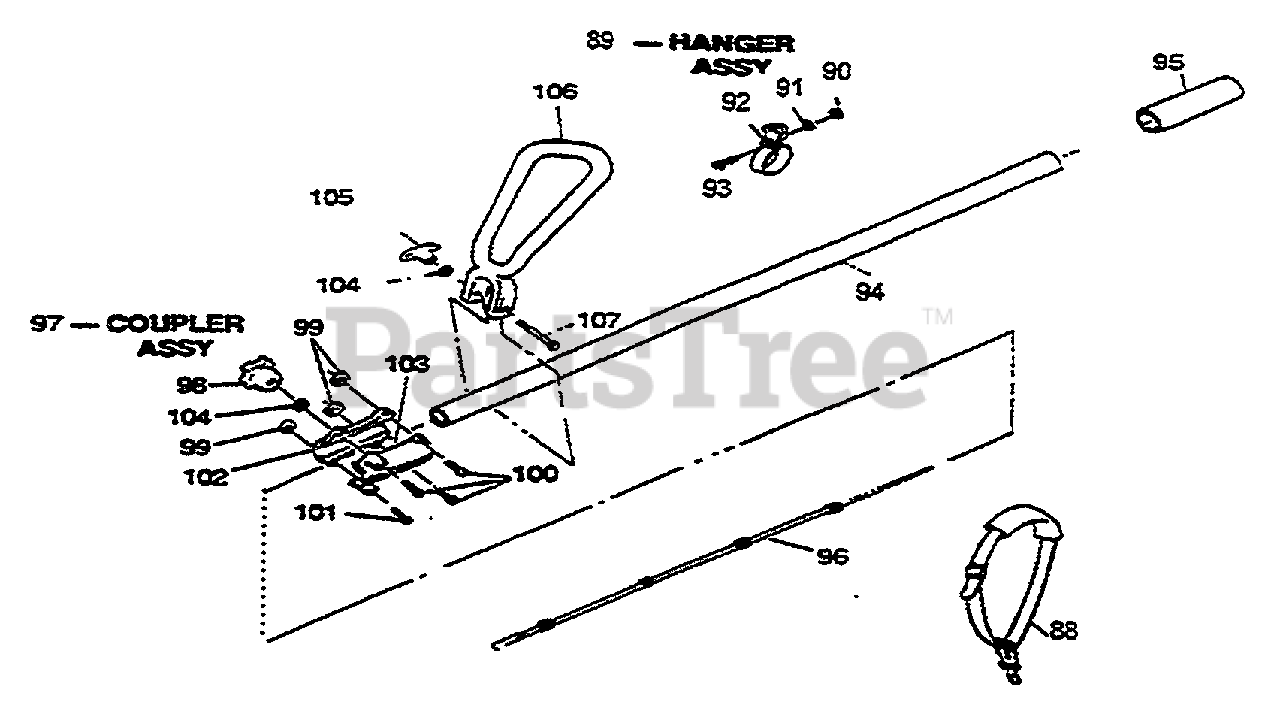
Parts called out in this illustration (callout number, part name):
88	HARNESS
89	HANGER ASSY
92	HANGER
94	TUBE ASSY
96	LINER & SHAFT ASSY
97	COUPLER ASSY
98	KNOB
100	BOLT
102	COUPLER RH.
103	COUPLER LH
105	KNOB
106	ASSIST HANDLE
107	BOLT
